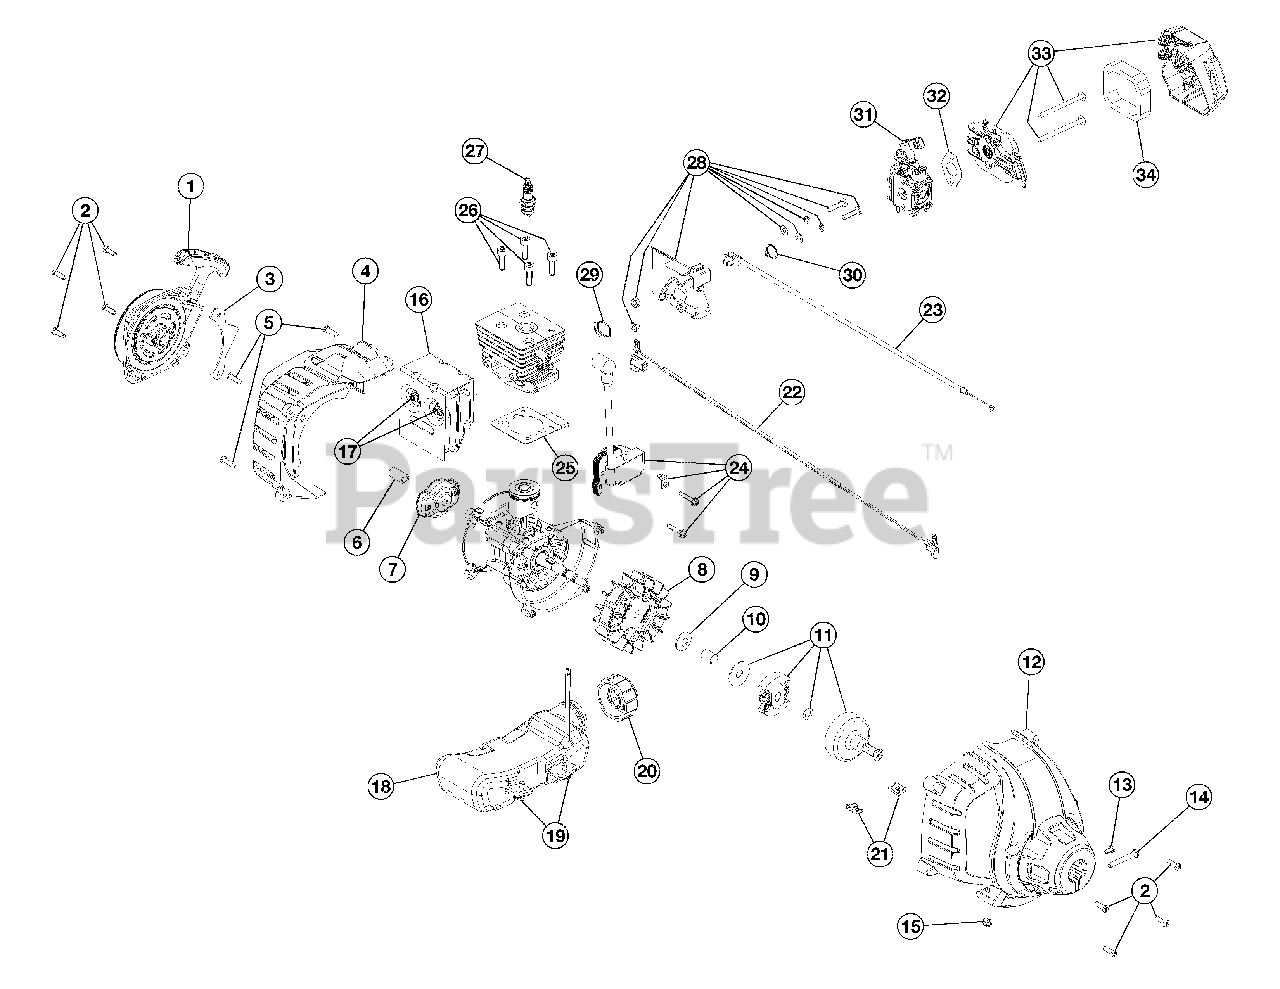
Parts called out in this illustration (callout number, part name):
1	Starter Assembly (Incl. 2 & 3)
2	Starter Screw
3	Starter Assembly Guard (Incl. 2)
4	Rear Engine Cover (Incl. 5)
5	Cover Screw
7	Pawl Assembly
8	Flywheel Assembly
11	Clutch Assembly
12	Clutch Cover Assembly (Incl. 2, 13 -15 & 22)
13	Anti-Rotation Screw
14	Clamp Screw
15	Clamp Nut
16	Muffler Assembly (Incl. 17 & 18)
17	Muffler Screw
18	Fuel Tank Assembly (Incl. 20 and 21)
21	U-shaped Nut
22	Lead Wires
23	Throttle Cable
24	Module Assembly
25	Cylinder Gasket
26	Cylinder Bolt
27	Spark Plug
28	Insulator Assembly (Incl. 30 and 31)
29	Insulator O-Ring
30	Carburetor O-Ring
31	Carburetor
32	Carburetor Gasket
33	Air Cleaner Assembly (Incl. 35)
34	Air Cleaner Filter
